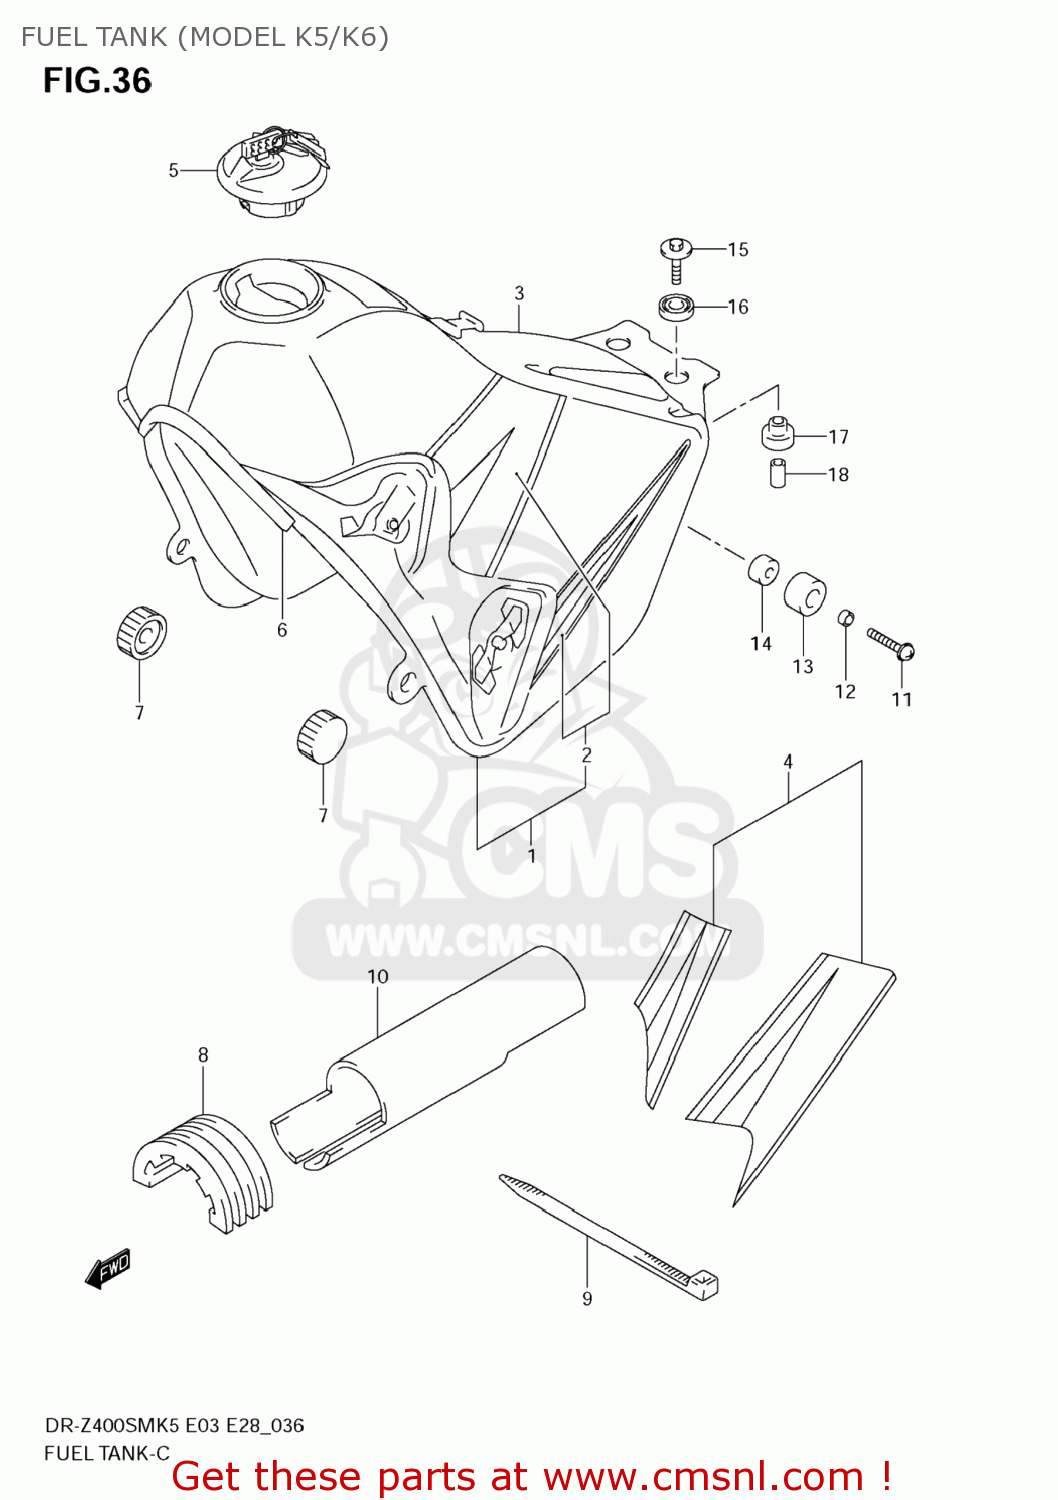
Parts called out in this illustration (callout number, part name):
1	TANK ASSY,FUEL(BLACK)
2	TAPE SET,FUEL TANK
3	TANK ASSY,FUEL(BLACK)
4	TAPE SET,FUEL TANK
5	CAP SET,FUEL TANK
6	MOLDING
7	CUSHION
8	CUSHION,FUEL TANK
9	CLAMP(L:300)
10	SHIELD,FUEL TANK
11	SCREW
12	SPACER(6.5X20X9)
13	CUSHION
14	SPACER(6.5X9X5)
15	BOLT(6X30)
16	CUSHION
17	CUSHION
18	SPACER(6.5X9X18)
